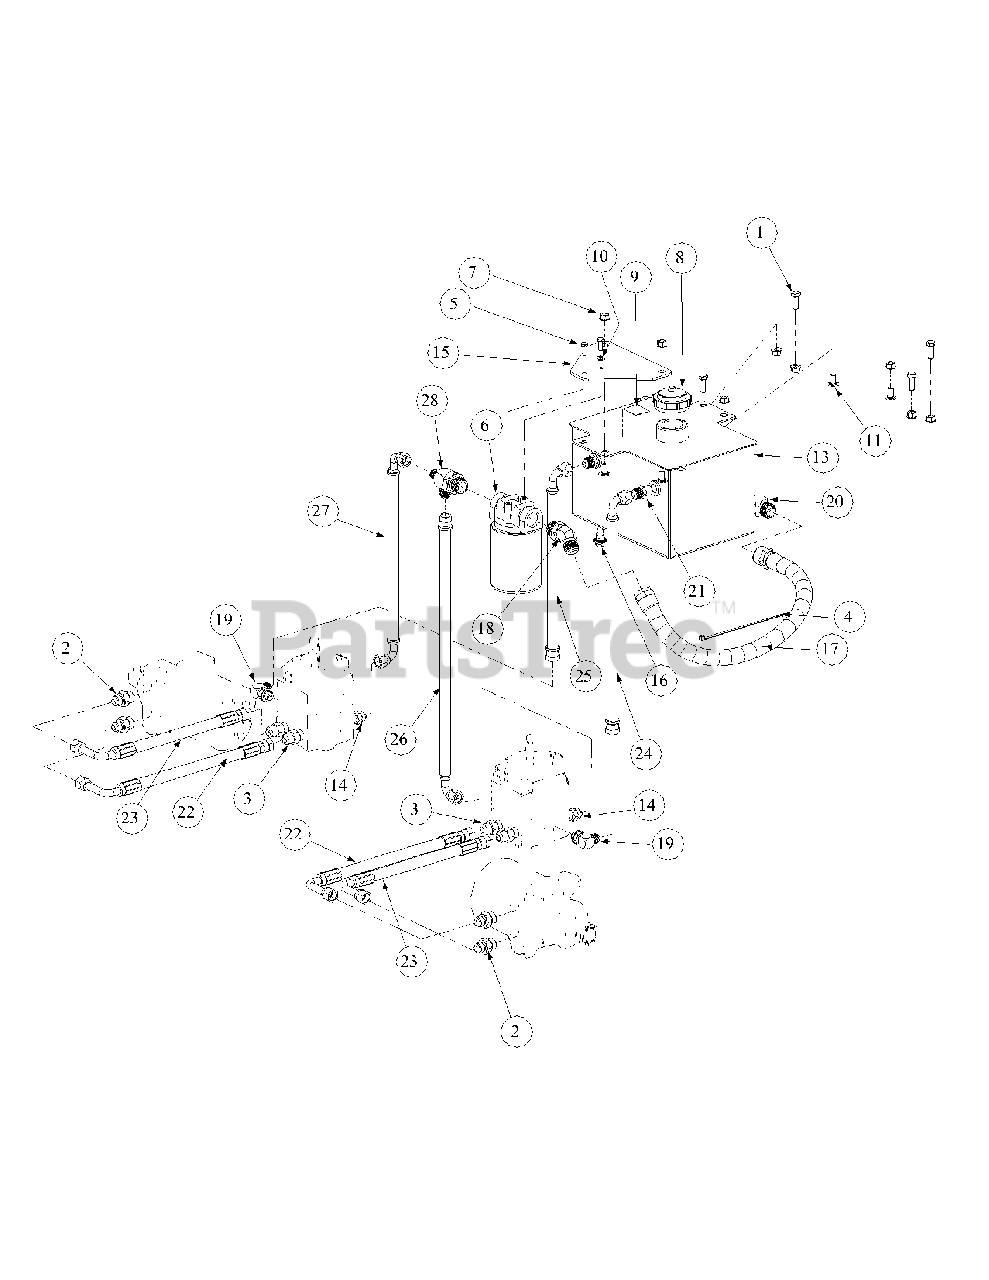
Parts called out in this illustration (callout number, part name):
1	Hex Cap Screw, 3/8-16, 1
2	Fitting 1/2 x 3/4 - O Ring
3	Fitting 1/2 x 1/2 - O Ring to Flare
4	Cable Tie, 3/16 x .05 x 7.4
5	Hex Cap Screw, 1/4-20, .75
6	Filter Head 3/4
7	Hex Nut Flange Lock, 3/8-16
8	Cap, Hydro Oil Tank
9	Decal Oil Only 20W50
10	Lock Washer, 1/4
11	Carriage Bolt, 3/8-16 x .75 LG.
13	Hydraulic Tank Assembly
14	Fitting Connector, 1/2 x 3/8
15	Oil Filter Mounting Plate
16	Oil Pan Drain Plug w/ Seal
17	Tank to Filter Hose Assembly
18	Fitting, 3/4 x3/4 x 45 degree
19	Elbow Fitting, 3/8 O-ring, 1/2 Flare
20	Fitting Elbow, 1/2 x 1/2
21	Fitting, 3/8 NPT, 1/2 Flare
22	Long Pressure Hose Assembly
23	Short Pressure Hose Assembly
24	17.75" Return Hose Assembly, RH
25	14.25" Return Hose Assembly, LH
26	21.25" Supply Hose Assembly, RH
27	15.50" Supply Hose Assembly, LH
28	Tee Fitting, 3/4 x 1/2 x 1/2
